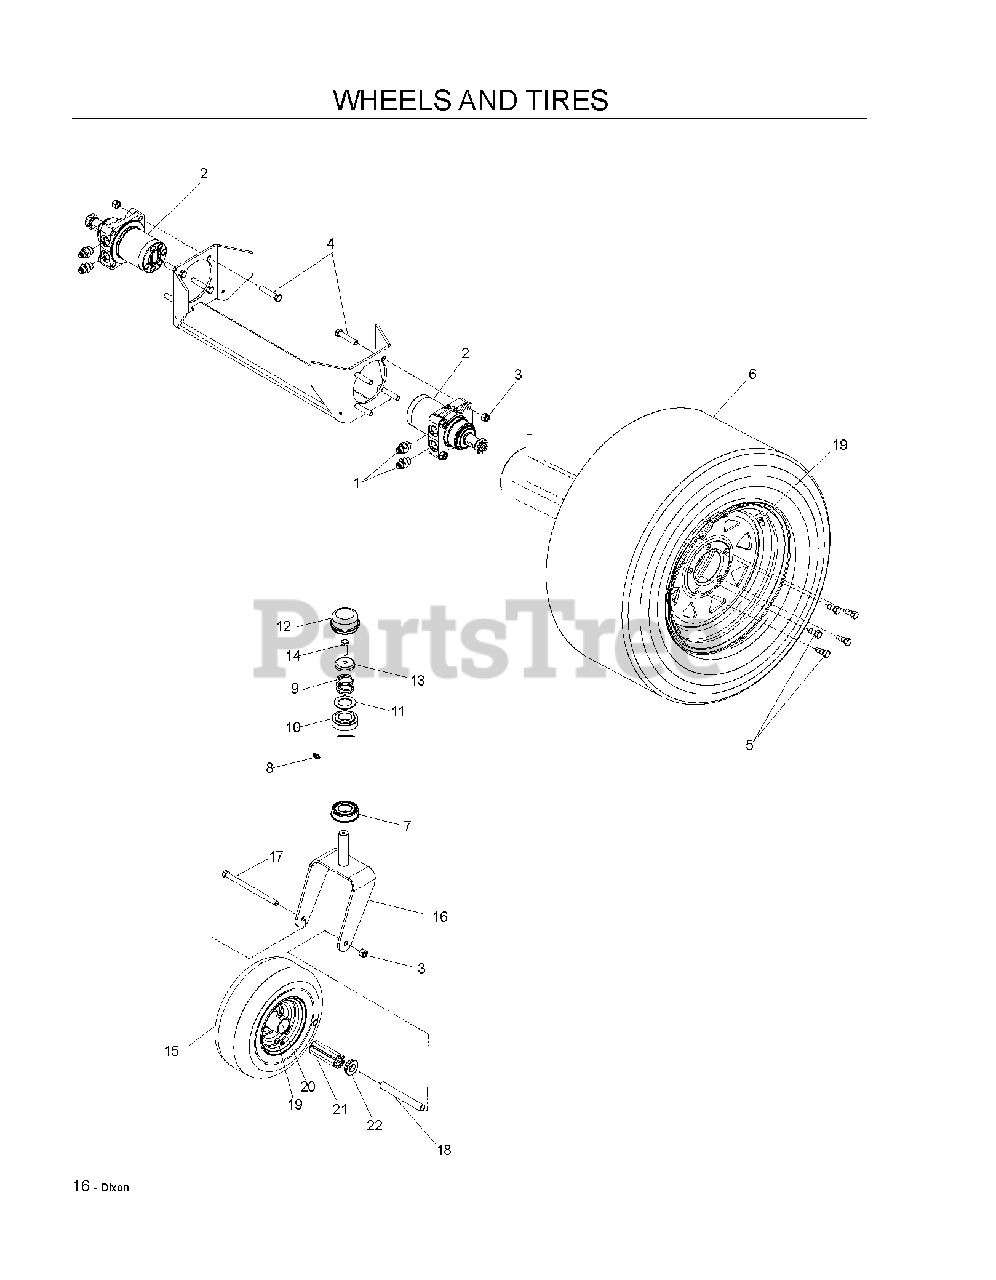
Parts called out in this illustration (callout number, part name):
1	CONNECTOR, STRAIGHT
2	WHEEL MOTOR, TJ
3	NUT 1/2-13 HEX NYLOC ZD
4	HCS 1/2C X 2 3/4
5	HUB BOLT
6	WHEEL.R.TS.23X10.5-12.C.MS
7	BEARING FLANGED
8	ZERK, 3/16, DRIVE IN
9	SPRING, CASTER
10	BUSHING, CASTER
11	WASHER, 1.025 ID X 1.64
12	GREASE CAP
13	CASTER.PLUG
14	HCS 5/16C X 1
15	TIRE.ASSEM.13X5-6.SMOOTH.SILVE
16	YOKE, CASTER - BLUE
17	SCREW 1/2C X 7 1/2 HEX CAP
18	SPACER, CASTER
19	VALVE STEM TR-412
20	ZERK 1/8 NPT
21	ROLLER BEARING
22	BEARING RETAINER
